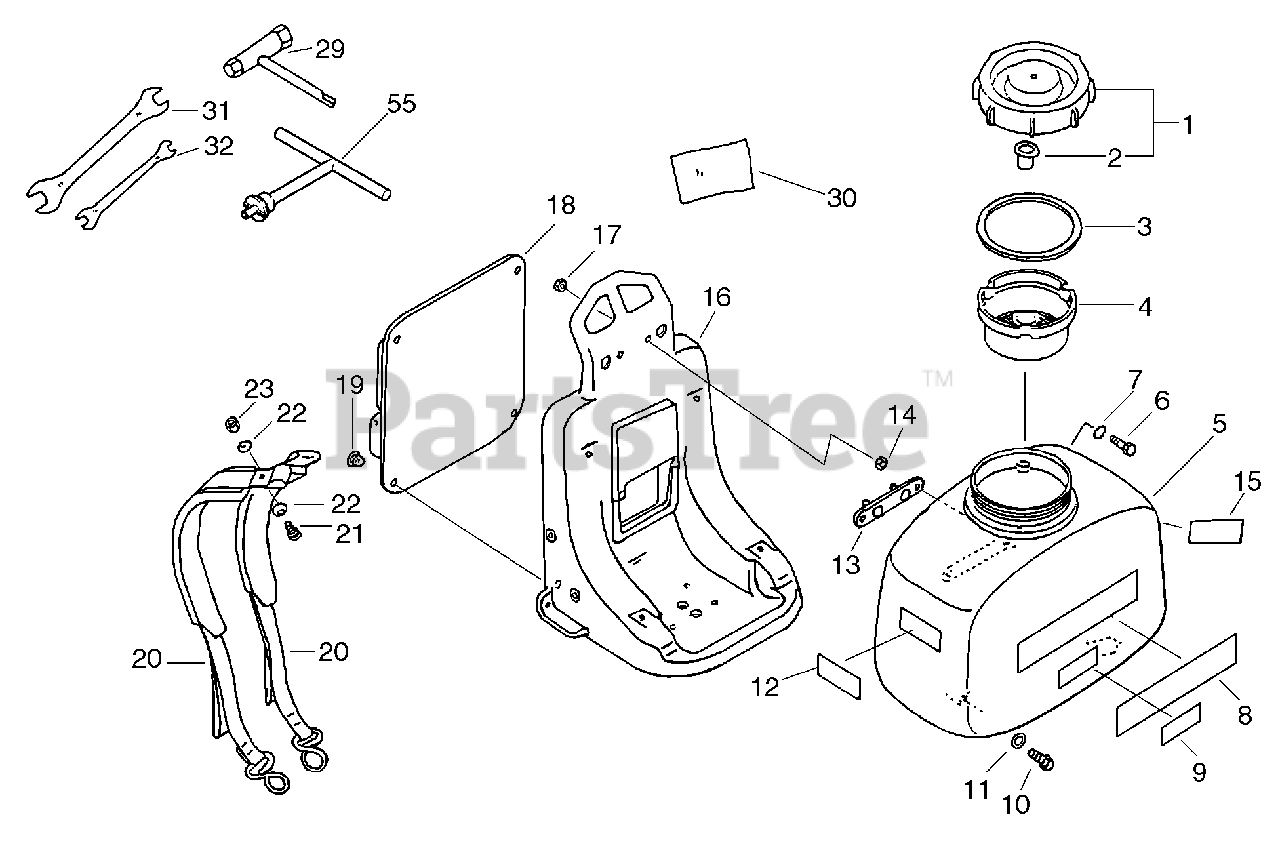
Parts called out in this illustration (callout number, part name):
1	CAP ASSY
2	VENT, TANK
7	O-RING - 10
8	LABEL - ECHO
9	LABEL - MODEL
12	LABEL - CAUTION
13	BRACKET, TANK
14	NUT - 6 -- FLANGE
15	LABEL - CAUTION
16	FRAME, BACKPACK
17	NUT - FLANGE
18	CUSHION, BACKPACK
21	SCREW - 5X14
23	LOCKNUT - 5
29	T-WRENCH - 17X19mm
30	POLY BAG
31	SPANNER - 14X17mm
32	SPANNER - 10X12mm
55	TOOL, DRIVER
